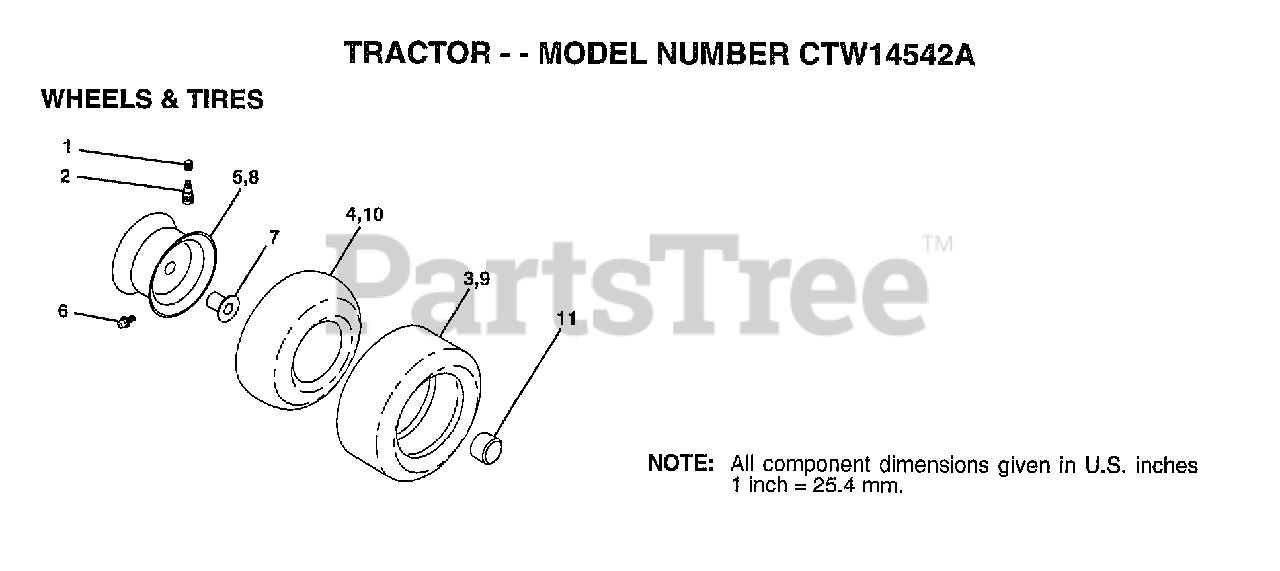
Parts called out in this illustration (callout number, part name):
1	VALVE CAP
2	VALVE STEM LT
4	TUBE.5.3/4.5/6
5	"RIM ASM 6"" FRT"
6	FITTING LT
7	"FLANGE, BEARING"
8	"RIM AS 8"" REAR"
9	TIRE.20X8-8
10	TUBE.18X9.5-8
11	HUB CAP
